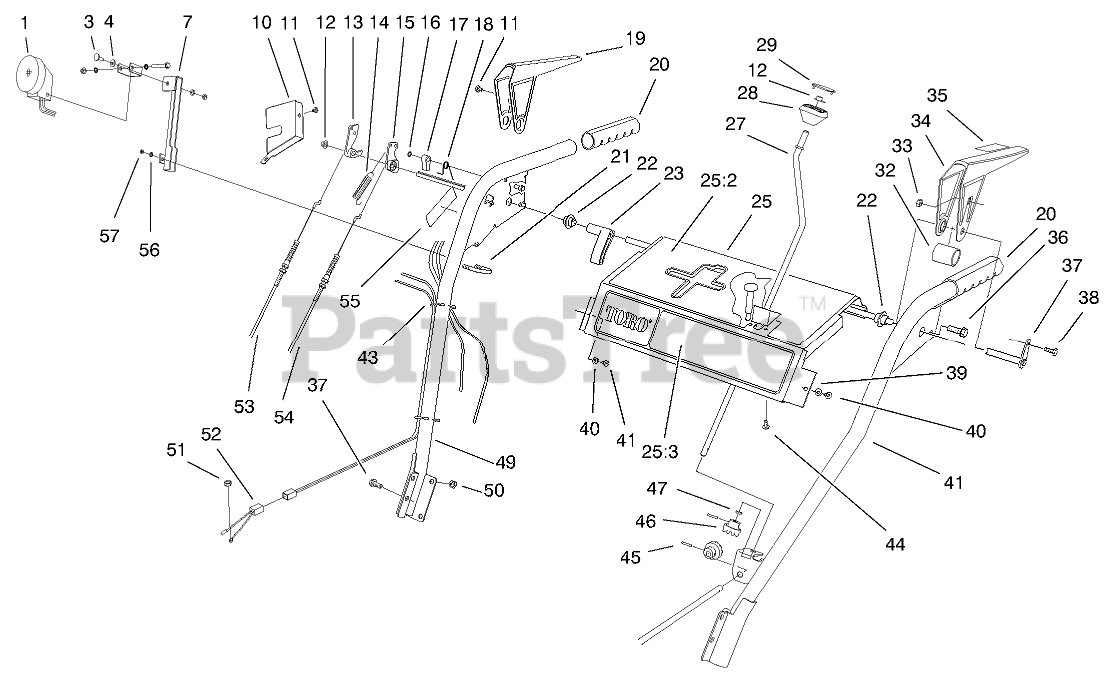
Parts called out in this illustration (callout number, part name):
1	Headlamp ASM (only on: 38087)
3	Screw-CARR (only on: 38087)
4	Washer-Flat (only on: 38087)
7	Mount-Light (only on: 38087)
10	COVER-LOCK, LEVER
11	SCREW-HH
12	RETAINER-PUSH ON
13	TANG-LOCKING
14	SPRING-EXTENSION
15	CAM-RELEASE
16	E-RING-RETAINER
17	LATCH-LOCKING
18	SPRING-TORSION
19	LEVER-TRACTION, RH
20	GRIP-HANDLE
21	U-Bolt (only on: 38087)
22	BUSHING-LEVER
23	LEVER-TRIP
25	Control Panel ASM (only on: 38087)
25	Control Panel ASM (only on: 38592)
25:2	Decal-Top, Panel (only on: 38592)
25:2	Decal-Control (only on: 38087)
25:3	Decal-Panel Front (only on: 38592)
25:3	Decal-Front Panel (only on: 38087)
27	CRANK-ROD, CHUTE
28	KNOB-CONTROL, CHUTE
29	COVER-KNOB
32	SPACER-LEVER, TRACTION
33	NUT-LOCK, NI
34	LEVER-TRACTION, LH
35	Decal-Lever (only on: 38592)
36	SCREW-HWHTF
37	CROSS ROD ASM
38	SCREW-HWH
39	WASHER-FLAT
40	SCREW-HWHTF
41	LH HANDLE ASM
43	TIE-CABLE
44	SCREW
45	PIN-SPRING
46	GEAR-UNIVERSAL
47	WASHER-RUBBER
49	Handle ASM (only on: 38592)
49	Handle ASM (only on: 38087)
49:2	Decal-Warning (only on: 38592)
49:2	Decal-Adjustment (only on: 38087)
50	NUT-LOCK, NI
51	Nut-Hex (only on: 38087)
52	Wire Assembly (only on: 38087)
53	CABLE-IMPELLER
54	CABLE-TRACTION
56	Washer-Flat (only on: 38087)
57	Nut-Lock (only on: 38087)
